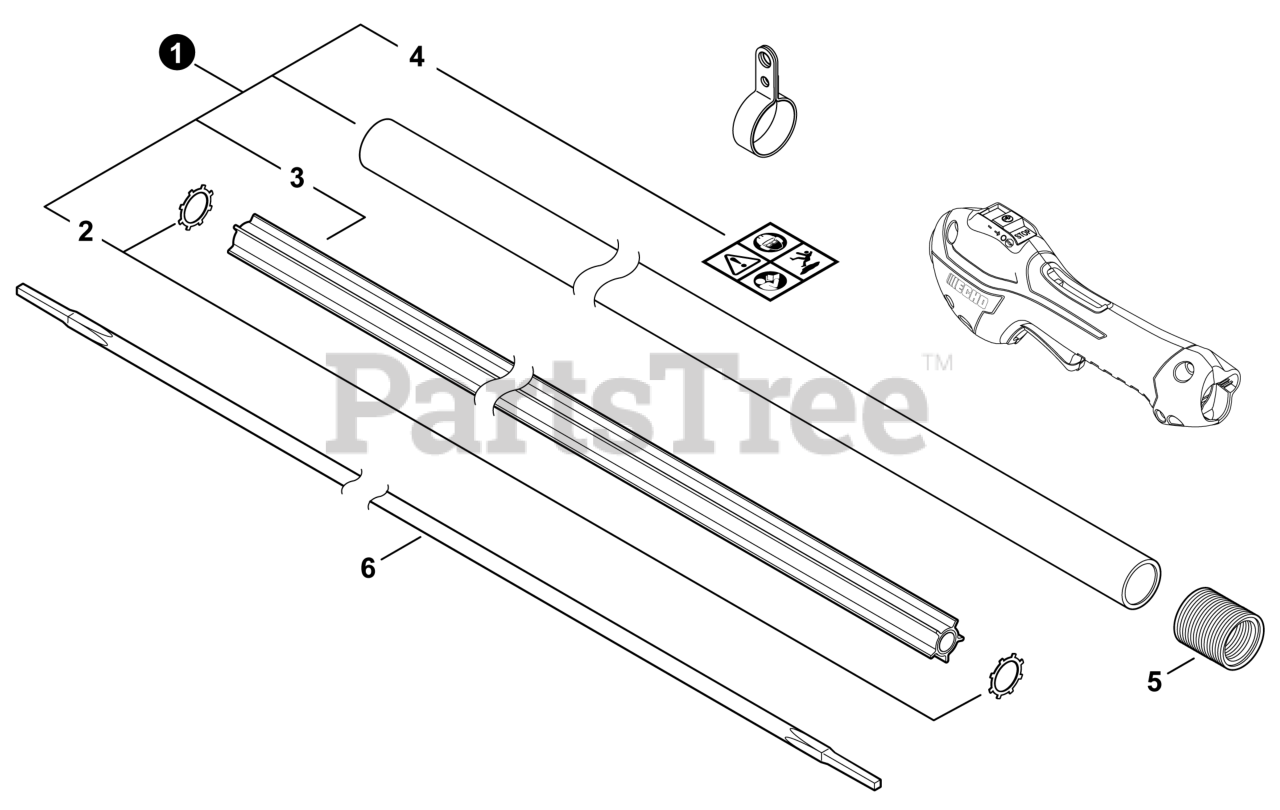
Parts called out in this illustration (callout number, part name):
1	MAIN PIPE ASSY
3	LINER - FLEXIBLE
4	LABEL - CAUTION
5	TUBE, FLEXIBLE
6	DRIVESHAFT - FLEXIBLE
